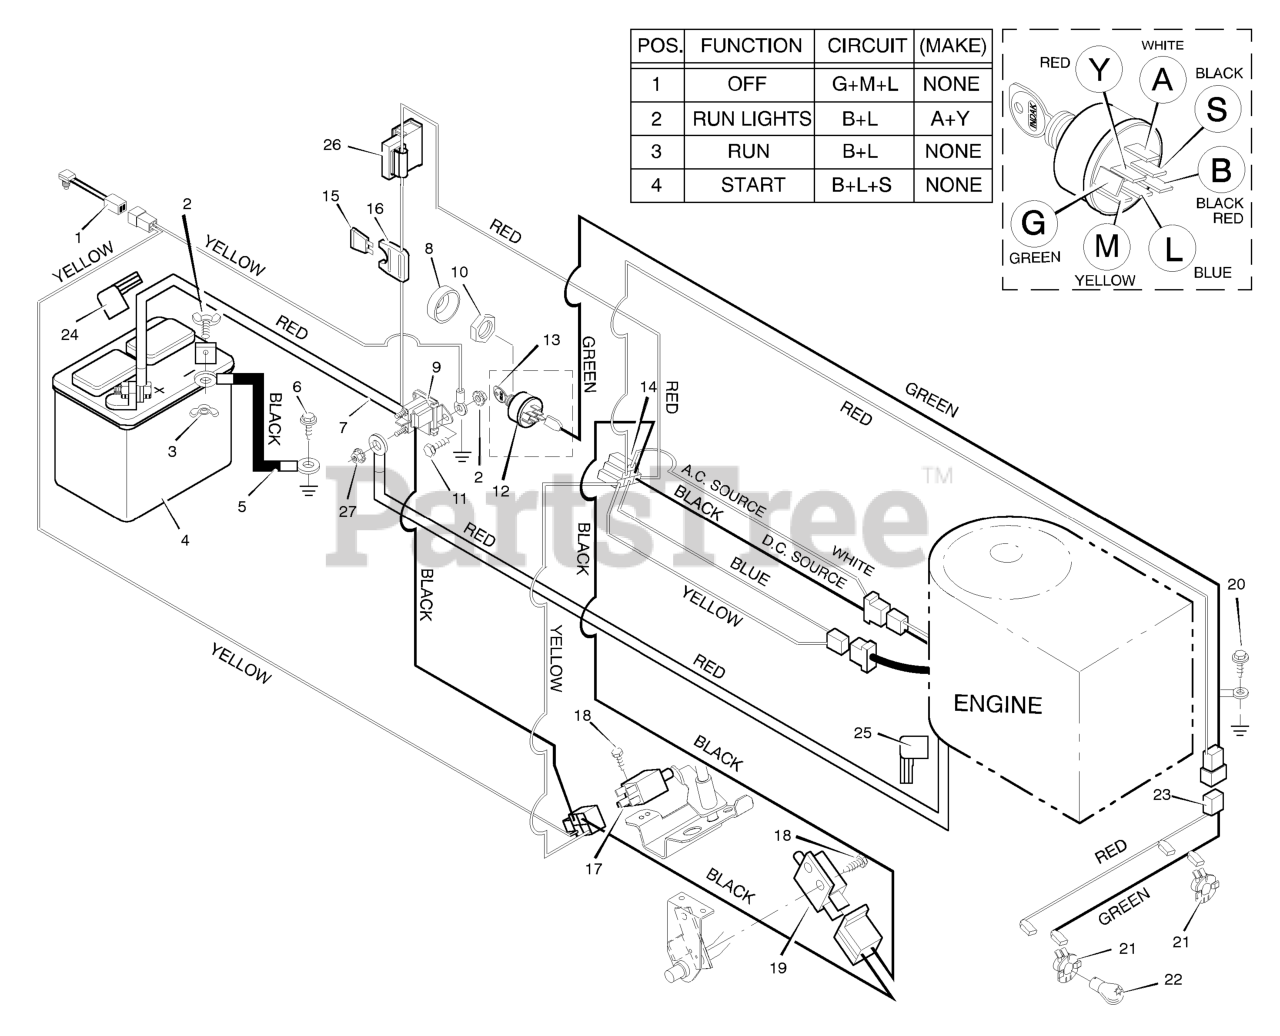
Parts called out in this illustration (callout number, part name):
1	Switch, Seat Sensor
3	Wingnut
4	Battery
5	Cable, Battery Ground
7	Cable, Red Battery
8	Cap, Ignition
9	Solenoid
10	Nut
12	Switch, Ignition
13	Key, Ignition
14	Harness, Chassis Wire
16	Holder, Fuse
19	Switch, Clutch
20	Screw
21	Socket, Light
22	Bulb, Light
23	Harness, Light Wire
24	Cover, Terminal
25	Cover,
26	Ammeter
27	Locknut
